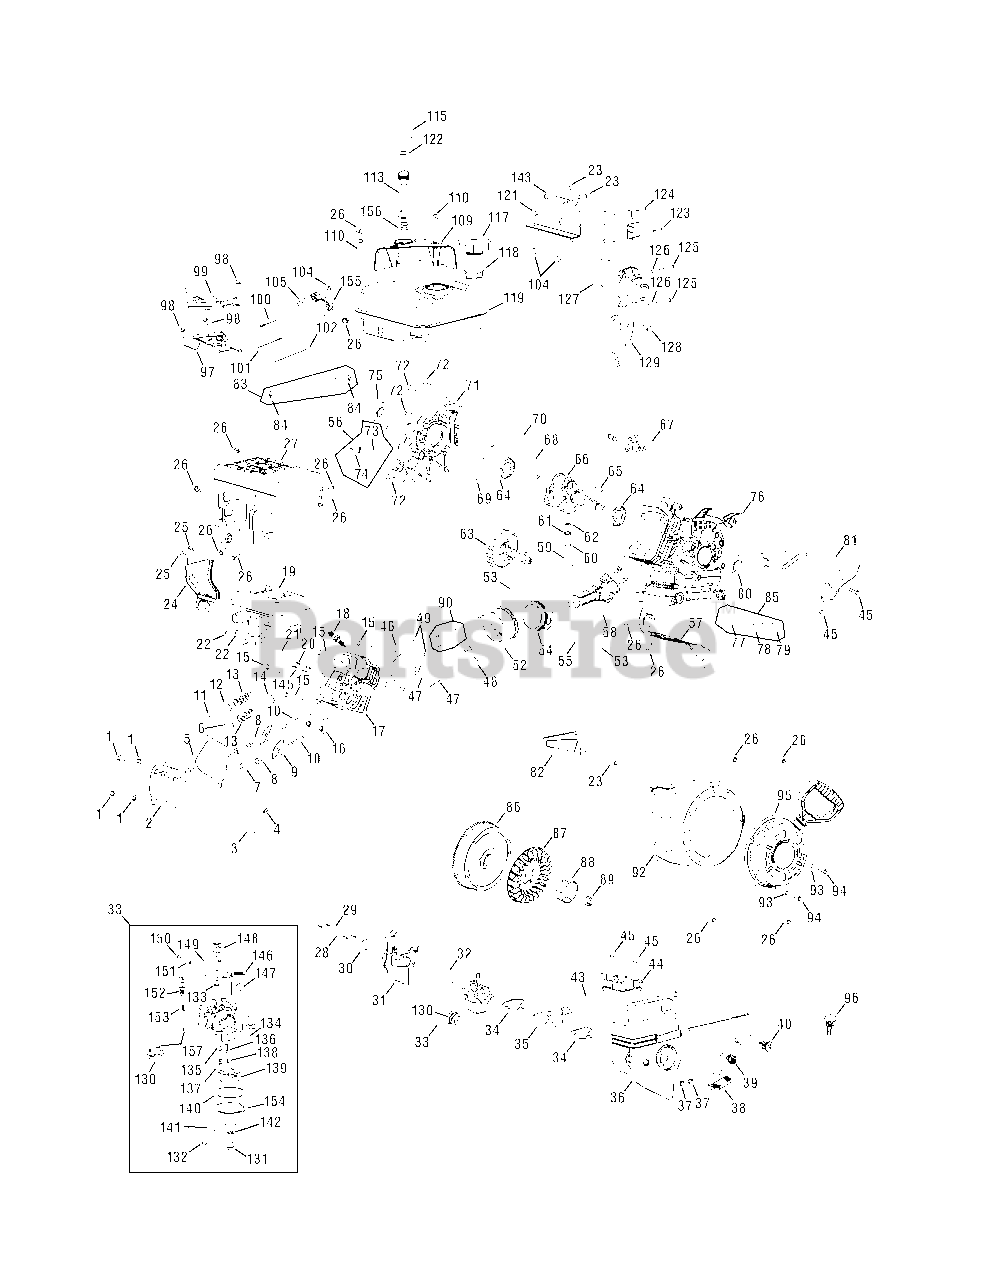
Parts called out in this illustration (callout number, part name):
2	Valve Cover
3	Breather Hose
4	Hose Clamp
5	Head Cover Gasket
6	Intake Valve Spring Seat
7	Pivot Locking Nut
8	Valve Adjusting Nut
9	Rocker Arm
10	Pivot Bolt
11	Exhaust Valve Adjuster
12	Exhaust Valve Spring Seat
13	Valve Spring
14	Intake Valve Seal
16	Push Rod Guide Plate
17	Cylinder Head - Complete
18	Spark Plug
19	Muffler Assembly
20	Stud
21	Muffler Gasket
24	Exhaust Pipe Shield
27	Muffler Shroud
28	Stud, M6 x117
29	Stud, M6 x 105
30	Carburetor Insulator Gasket
31	Carburetor Insulator Plate
32	Carburetor Gasket
33	Carburetor Assembly
34	Carburetor Gasket Plate
35	Choke Control Bracket
36	Engine Shroud
38	Choke Knob
39	Throttle Control Knob
40	Ignition Switch
43	Choke Push Rod
44	Heater Box
46	Cylinder Head Gasket
47	Push Rod Kit (incl. intake and exhaust rod)
48	Tappet
49	Dowel Pin
52	Piston Ring Set
53	Piston Pin Snap Ring
54	Piston
55	Piston Pin
56	Oil FIll Plug Assembly
57	Air Shield
58	Connecting Rod Assembly
59	Governor Arm Shaft
60	Washer
61	Governor Seal
62	Cotter Pin
63	Camshaft Assembly
64	Radial Ball Bearing
65	Flywheel Key
66	Crankshaft Assembly
67	Governor Gear/Shaft Assembly
68	Dowel Pin, 7 x 14
69	Dowel Pin, 9 x 14
70	Crankcase Cover Gasket
71	Case Cover
71	Cover Complete, Left Crankcase
72	Cover Bolt
73	O-Ring
74	Oil FIll Plug
74	Oil Fill Plug
75	Oil Seal
76	Crankcase
77	Oil Drain Pipe
78	Washer
79	Oil Drain Plug Washer
80	Oil Seal
81	Ignition Coil
82	Air Flow Shield
83	Fuel Line Kit (incl. clamps and fuel line)
84	Hose Clamp
85	Oil Drain Assembly, includes 77, 78, 79
87	Cooling Fan
88	Starter Cup
89	Nut
90	Valve Kit (incl. intake and exhaust valve)
90	Valve Kit
92	Blower Housing
93	Washer
95	Recoil Starter Assembly
96	Ignition Key
97	Throttle Control Assembly
99	Governor Shield
100	Governor Spring
101	Throttle Return Spring
102	Governor Rod
104	Nut
109	Engine/Dipstick Cover
113	Dipstick Tube
115	Dipstick
117	Fuel Cap Assembly
118	Fuel Level Indicator
121	Switch Housing MTG Bracket
122	O-Ring
123	Bolt, M4 x 55
124	Bolt, M4 x 60
126	Dowel Pin
127	Electric Starter
129	Blower Housing Shield
130	Primer
131	Bolt
132	Drain Bolt
133	Gasket, Throttle Plate
134	Float Pin
135	Emulsion Tube
136	Needle Valve
137	Main Jet
138	Needle Valve Spring
139	Float
140	Fuel Bowl Gasket
141	Fuel Drain Plug Gasket
142	Fuel Bowl Gasket
145	Muffler Stud Assembly
146	Choke Shaft
147	Choke Plate
148	Throttle Shaft
149	Throttle Plate
150	Screw, M3×5
151	Lock Washer
152	Idle Jet Assembly
153	Idle Speed Adjusting Screw
154	Fuel Bowl
155	Governor Arm Bracket
155	Hose Clamp
156	O-Ring
